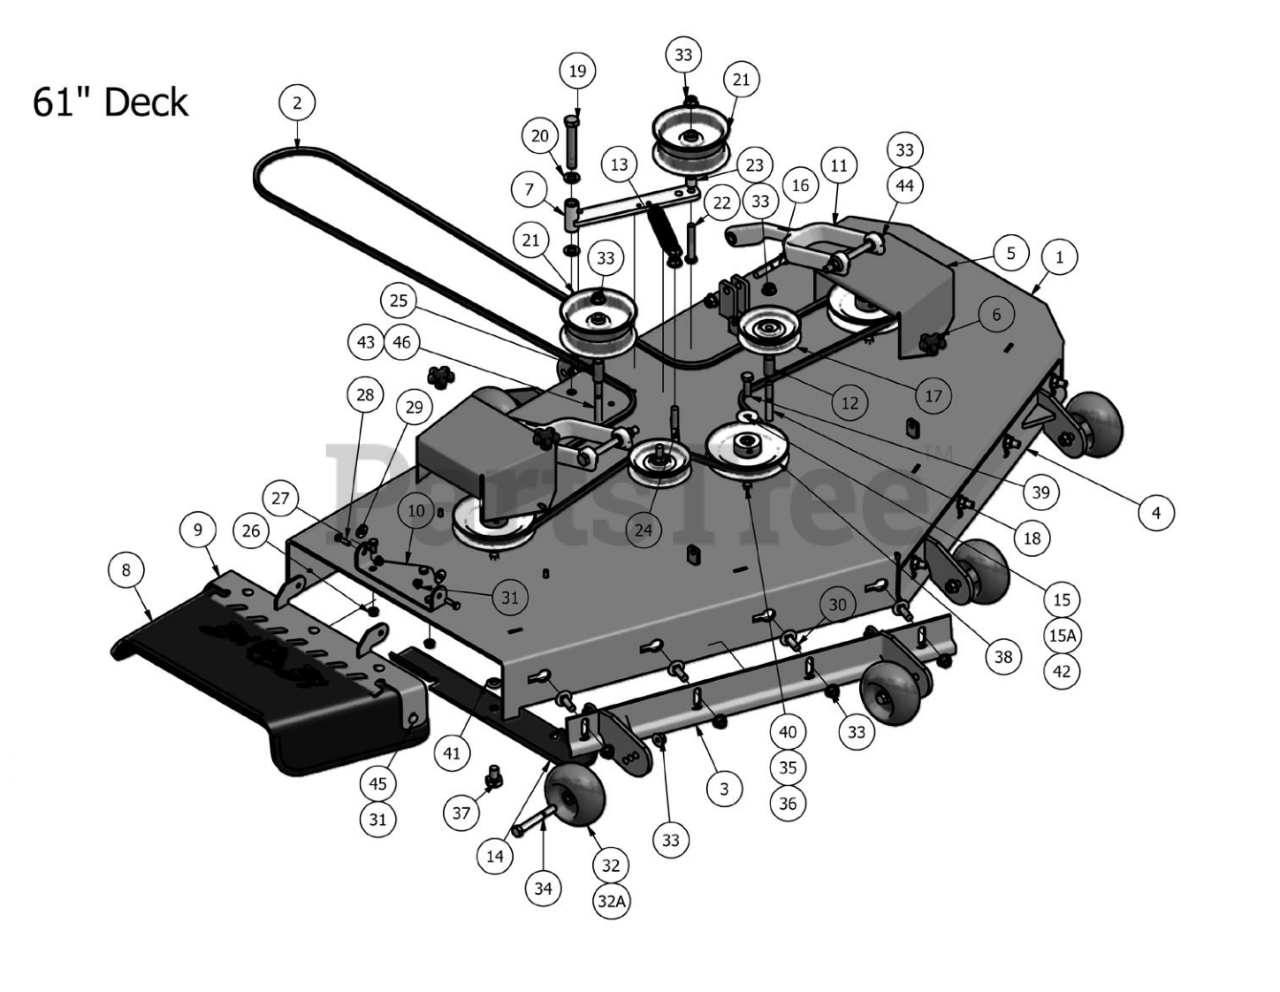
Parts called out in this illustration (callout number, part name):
1	61" Outlaw Deck (Welded Assembly)
2	B176 belt for 61 inch Outlaw
3	61 Outlaw Adjustable Deck Front (Right)
4	61 Outlaw Adjustable Deck Front (Left)
5	Plastic Pulley Cover
6	5/16" Knob
7	Deck Idler 2009
8	Rubber Discharge Chute
9	60" Discharge Chute Upper Hanger Plate
10	Discharge Chute Hanger (deck mounted)
11	Deck Arm Assembly
12	Pup Pulley Spacer
13	Deck Idler Spring 2009
14	61 inch Fusion Blade
15	Spring Blade Cupped Washer
15A	5/16" Set Screw
16	1/2 x 2-1/2 Hex Bolt
17	4 3/4" Idler Pulley
18	1/2 x 3-1/2 Flange Bolt - Grade 8
19	5/8" x 4" Hex Bolt
20	.635 ID Plastic Washer
21	5 3/4" Flat Idler Pulley- 32FI-92-008
22	1/2" x 3" Hex Bolt
23	3/4 OD x 1/2 ID x 3\4 Length
24	1/2 x 2" Carriage Bolt
25	1 3/4" Pulley Spacer
26	3/8-16 Hex Flange Nuts Zinc w/Serrations
27	3/8" x 3/4" Hex Bolt
28	5/16-18 x 1 Grade 5 Hex bolt Zinc
29	.360ID Plastic Washer
30	1/2 x 1-1/4 Carriage Bolt
31	5/16-18Nylon Insert flange Nut zinc Orange Insert
32	Anti-Scalp Rollers
32A	Complete Roller Assembly
33	1/2-13 Nylon Insert Flangenut Zinc Orange Nylon
34	1/2" x 4" Bolt (Grade 8)
35	3/8" Hex Nut
36	3/8" Lock Washer
37	5/8-18 X 1-1/2 GR 8 Hex Bolts Zinc Yellow
38	6 1/4" Drive Pulley
39	1/2" x 1 1/2" Hex Bolt
40	3/8-16 x 1-1/4 GR 5 Hex Bolt Zinc
41	5/8 Lock Washer Zinc
42	1/4 X 1 Square Key
43	1/2" Washer (Grade 8)
44	1/2" x 5 1/2" Bolt
45	5/16" x 1 1/4" Carriage Bolt
46	1/2" x 4 1/2" Bolt (Grade 8)
